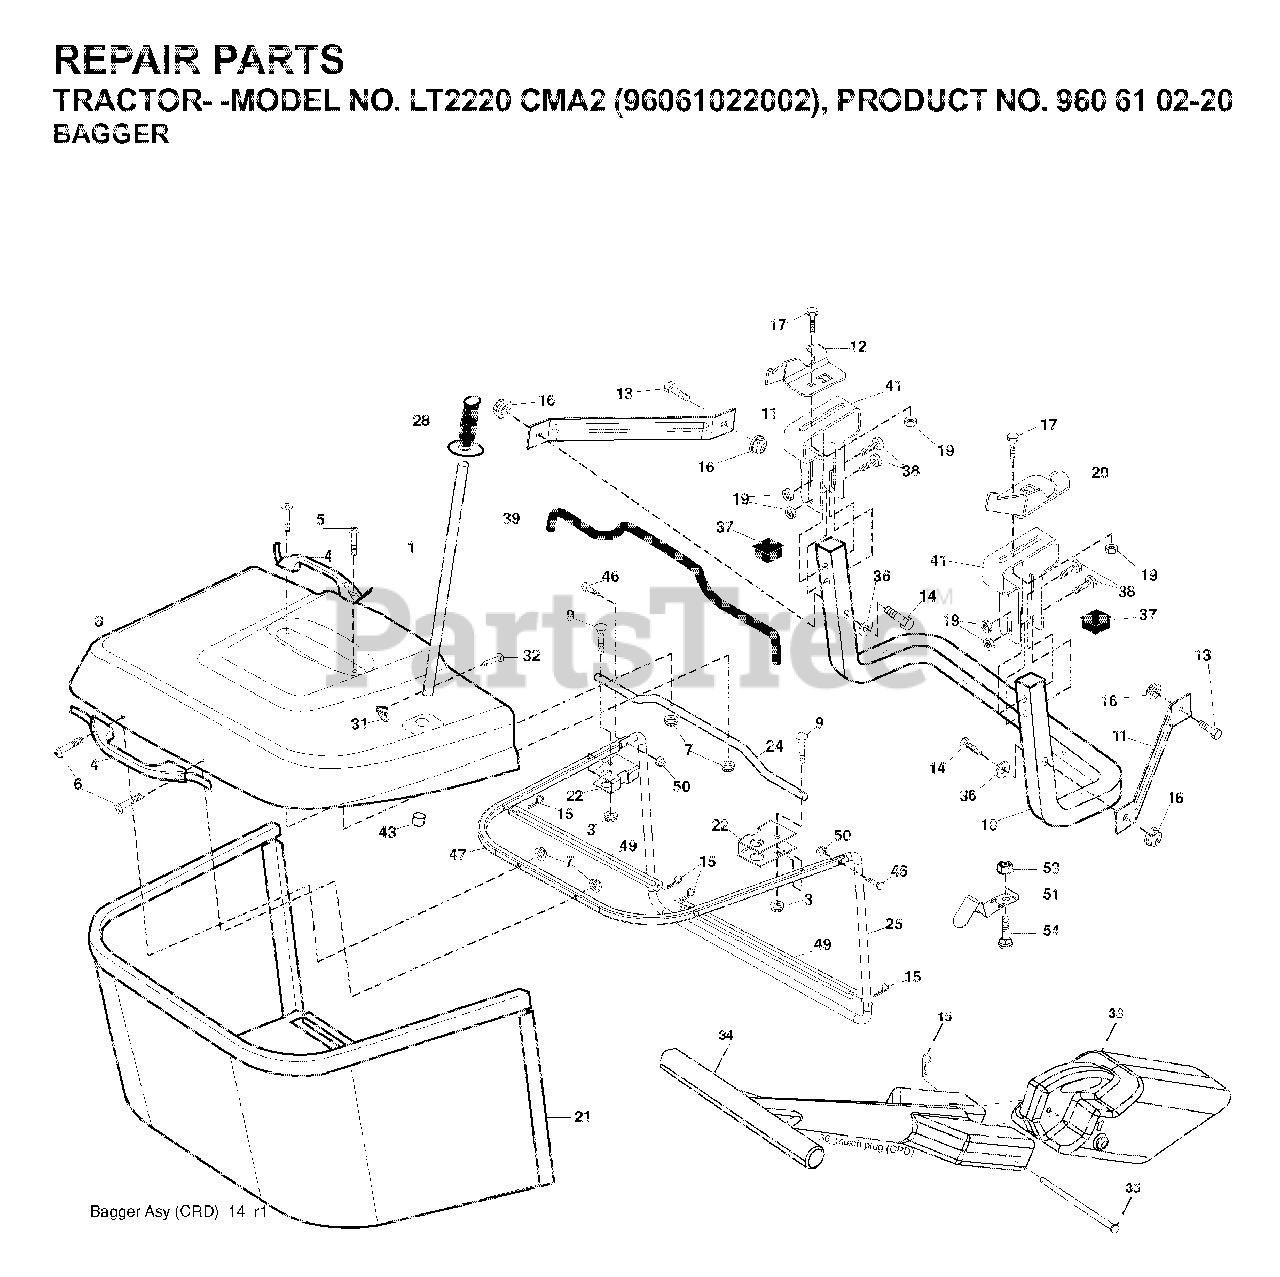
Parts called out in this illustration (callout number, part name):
1	TUBE HANDLE
3	NUT T
5	SCREW.PAN.HEAD
11	BRACKET
14	BOLT-HEX EAK
15	RETAINER-SPRNG RB
16	NUT LOCK FLG 3/8-16 UNC
17	BOLT
19	NUT LOCK HEX FLANGE 5/16-18
20	BRKT.PIVOT.RH.CRD
21	BAGGER.ASM.CRD.2007
22	BRACKET
24	TUBE
28	GRIP.HANDLE.BLACK
31	RETAINER CLIP
32	RIVET,DRILLED
33	MULCH PLUG, CTH150
35	PIN
38	BOLT.5/16-18X2.5
39	SEAL.BAGGER.CRD
41	BRKT, BAGGER
43	PLUG, TUBING END
46	BOLT.CARRIAGE.5/16-18
50	NUT.71038.31-18.HEX.NYLOCK
53	NUT
54	BOLT
